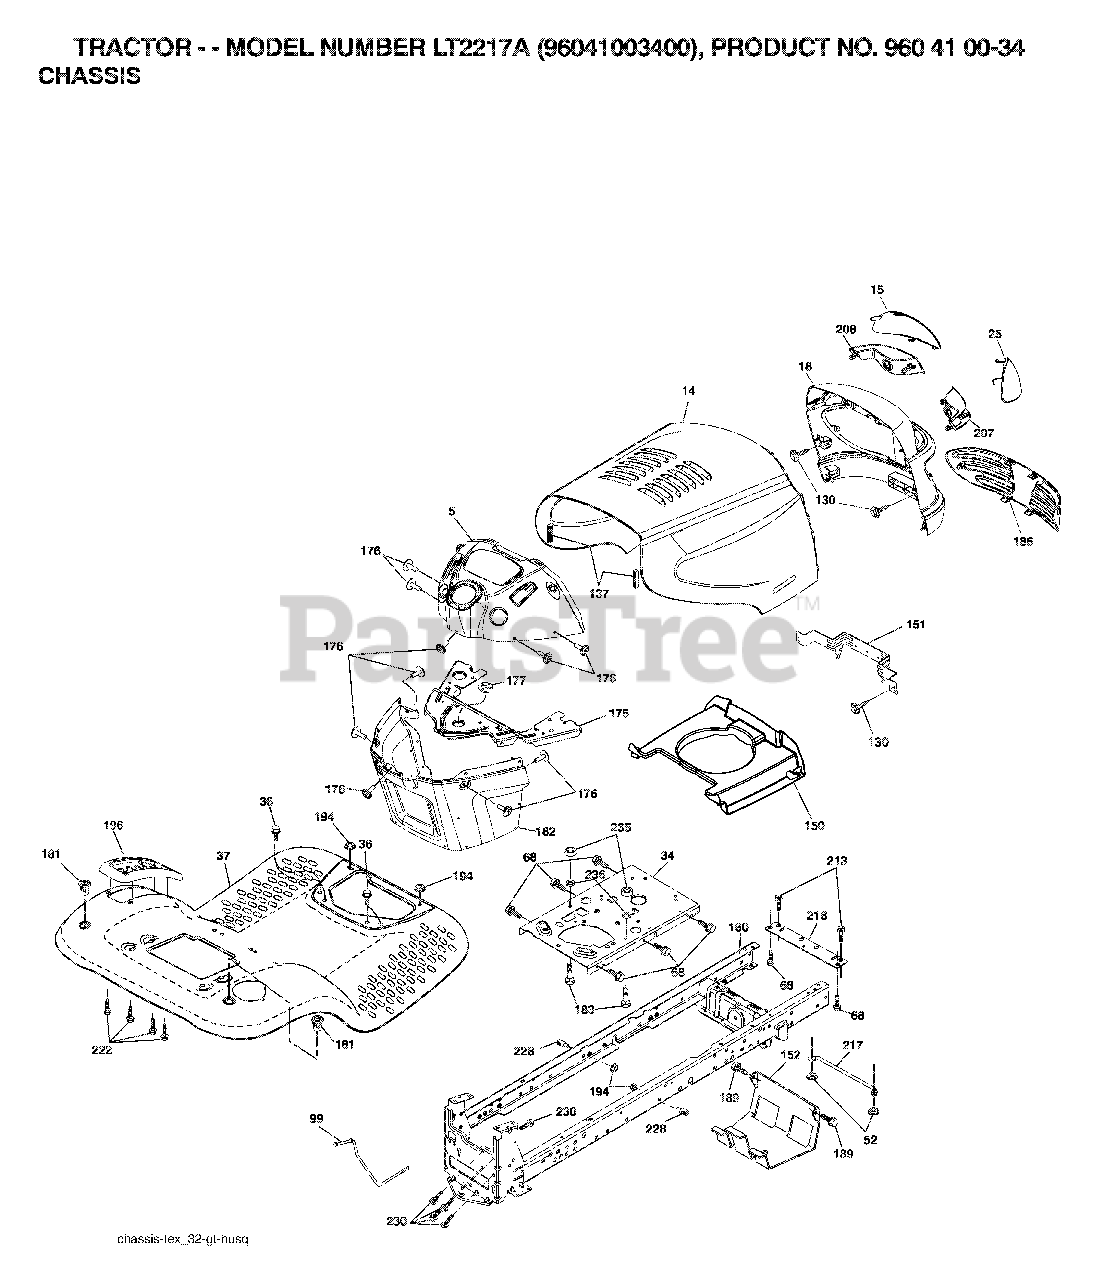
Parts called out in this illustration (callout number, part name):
34	PLATE.ENGINE.WELDED.CHASSIS
36	SCREW 3/8-16X3/4
52	LOCKNUT
99	ROD ASM BYPASS
130	SCREW
137	BUMPER.HOOD.LARGE.1.75"
151	BRACKET PIVOT
152	SHIELD BROWNING
175	CROSSMEMBER.LT
176	SCREW.#10-24X5/8.RN.QU
177	BUSHING STEERING
180	CHASSIS
181	FEND/FTRST.PCH.CPH.NFW
182	DASH.LOWER.LT.CCS
183	BOLT.5/16-18X1-1/4 FULL.THREAD
189	SCREW
194	NUT LOCK HEX FLANGE 5/16-18
196	CONSOLE.ASM.DECK.LIFT.TLT.BLAC
207	BEZEL GRILL RH
208	BEZEL GRILL LH
213	BOLT
217	ROD PIVOT CHASSIS/HOOD
218	X-PIECE.HOOD.STOP.NON/
222	SCREW.1/4-20X5/8
228	STUD.FASTNER.W/ANTI-ROTATE
230	SHOULDER BOLT 5/16-18TT
235	SPACER FENDER
236	NUT.CENTERLOCK.5/16-
